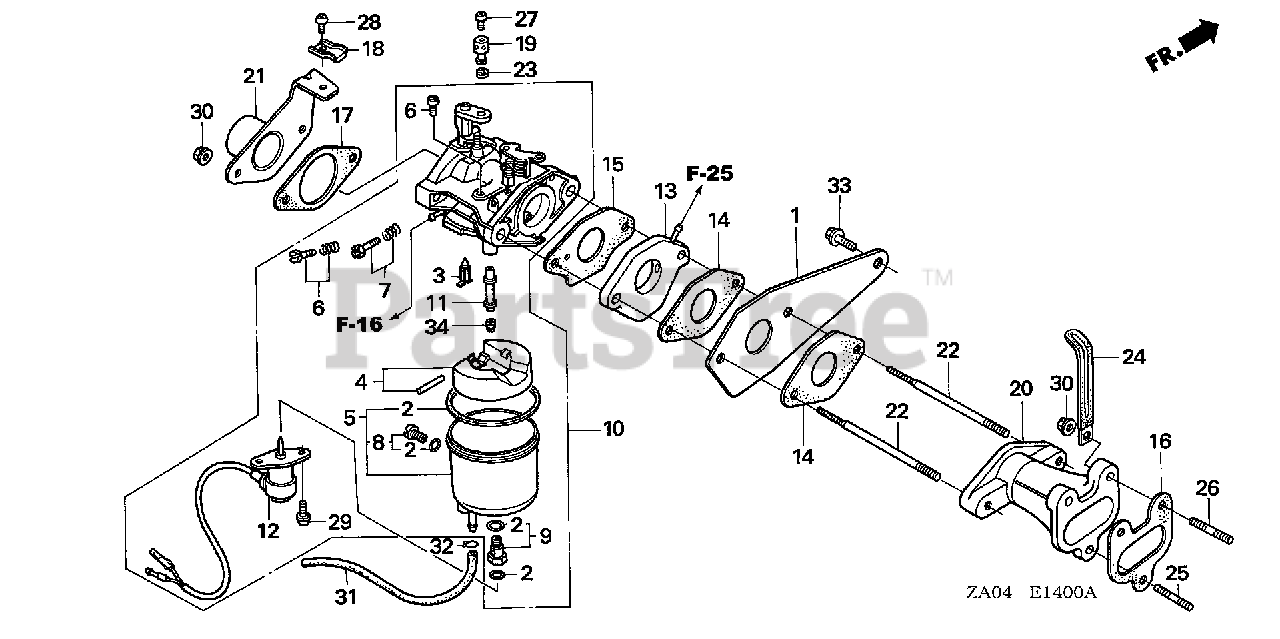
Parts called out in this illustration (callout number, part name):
1	STAY, TIMING BELT
2	GASKET SET
3	VALVE SET, FLOAT
5	CHAMBER SET, FLOAT
6	SCREW SET A
7	SCREW SET A
8	SCREW SET, DRAIN
10	CARBURETOR ASSY. (BB50A A/B) (NOT AVAILABLE)
11	NOZZLE, MAIN (NOT AVAILABLE)
12	VALVE ASSY., SOLENOID
13	INSULATOR, CARBURETOR (NOT AVAILABLE)
14	GASKET, INSULATOR
15	GASKET, CARBURETOR
16	GASKET, IN. MANIFOLD
17	GASKET, AIR CLEANER
18	HOLDER, CONTROL CABLE
19	HOLDER, CABLE
20	MANIFOLD, IN. (NOT AVAILABLE)
21	PIPE, AIR IN. (NOT AVAILABLE)
22	BOLT, STUD (8X110)
23	CIRCLIP (5MM)
24	CLIP, WIRE HARNESS
25	BOLT, STUD (6X18)
26	BOLT, STUD (6X35)
26	BOLT, STUD (6X28)
27	SCREW, PAN (4X8)
28	SCREW, PAN (5X10)
29	SCREW-WASHER (5X12)
30	NUT, FLANGE (6MM)
31	BULK HOSE, FUEL (3.5X3000) (3.5X320)
32	CLIP, TUBE (B7)
33	BOLT, FLANGE (6X12)
34	JET, MAIN (#98)
34	JET, MAIN (#100)
34	JET, MAIN (#102)
